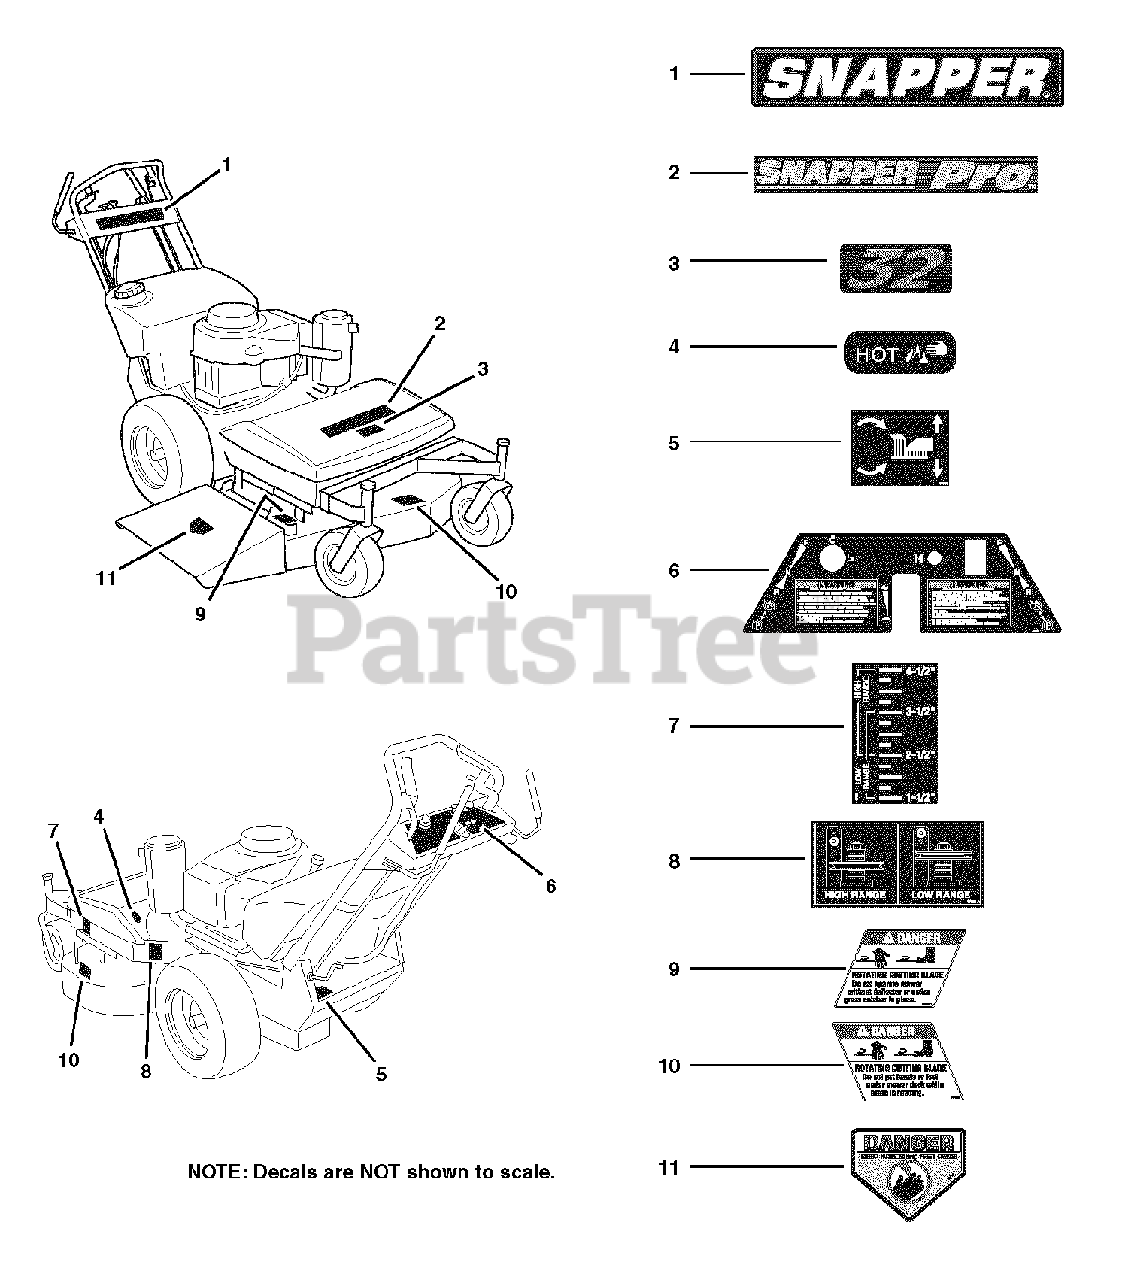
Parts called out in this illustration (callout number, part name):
1	DECAL, Snapper
2	DECAL, Snapper Pro
3	DECAL, 32
4	DECAL, Hot
5	DECAL, Cut Height Adjust
6	DECAL, Control Panel
7	DECAL, Deck Height
8	DECAL, Pulley Position
9	DECAL, Danger (Chute In Place)
10	DECAL, Danger (Hand Under Deck)
11	DECAL, Danger
